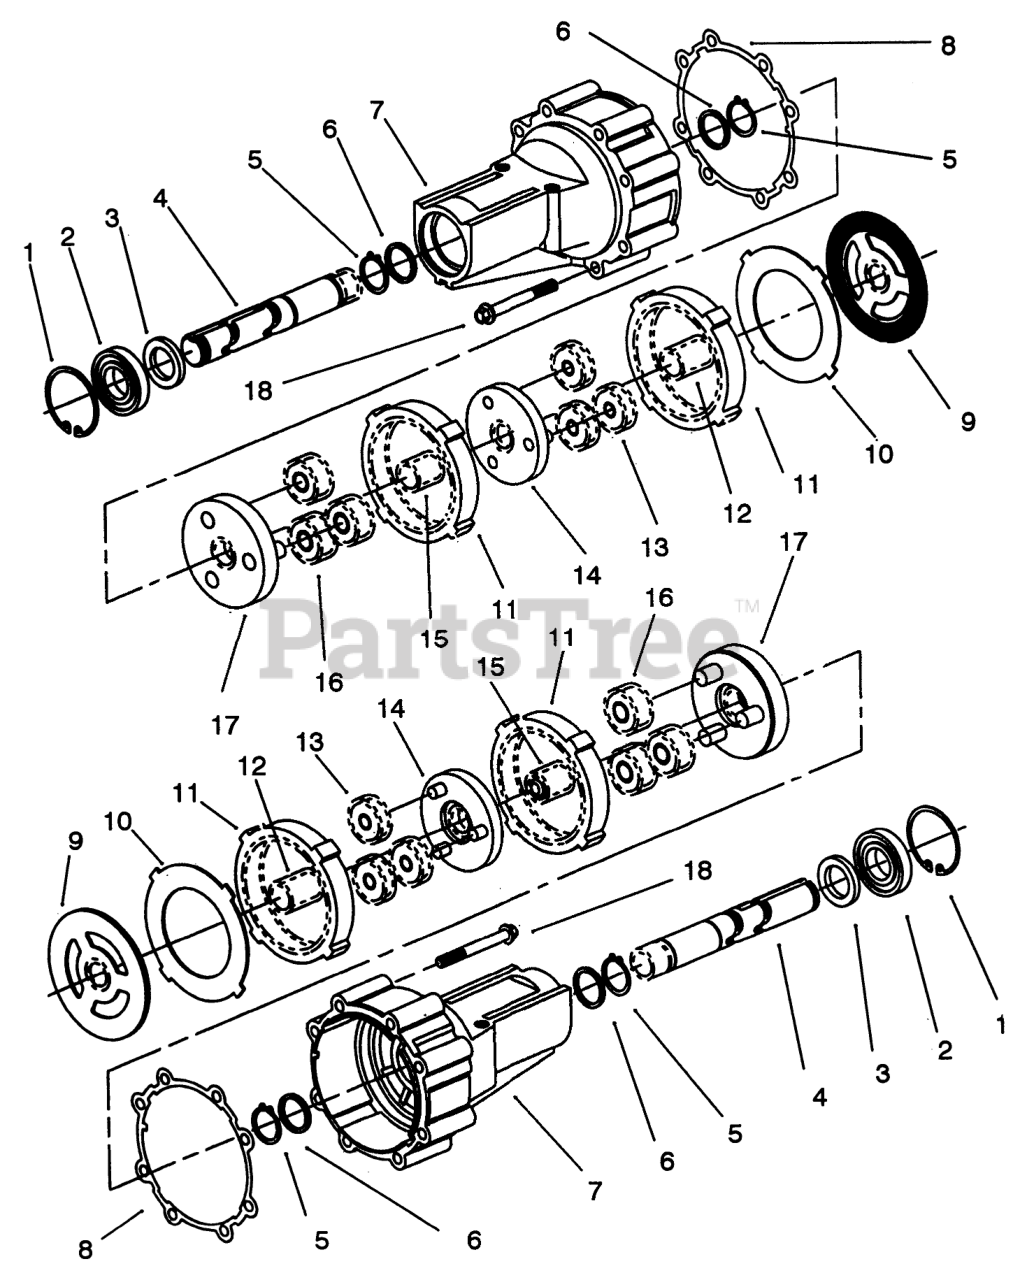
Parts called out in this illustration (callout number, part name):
1	RETAINING RING
2	BALL BEARING
3	RADIAL LIP SEAL
4	AXLE SHAFT
5	RETAINING RING
6	THRUST WASHER
7	AXLE HOUSING
8	Gasket-Axle Housing
9	REACTION PLATE
10	BACKUP PLATE
11	57 TOOTH RING GEAR
12	15 TOOTH FIRST GEAR
13	21 TOOTH PLANET. GEAR
14	15 TOOTH PRIMARY CARR.
15	15 TOOTH SECOND GEAR
16	21 TOOTH SECOND GEAR
17	SECONDARY CARRIER
18	5/16 HEX HEAD SCREW
